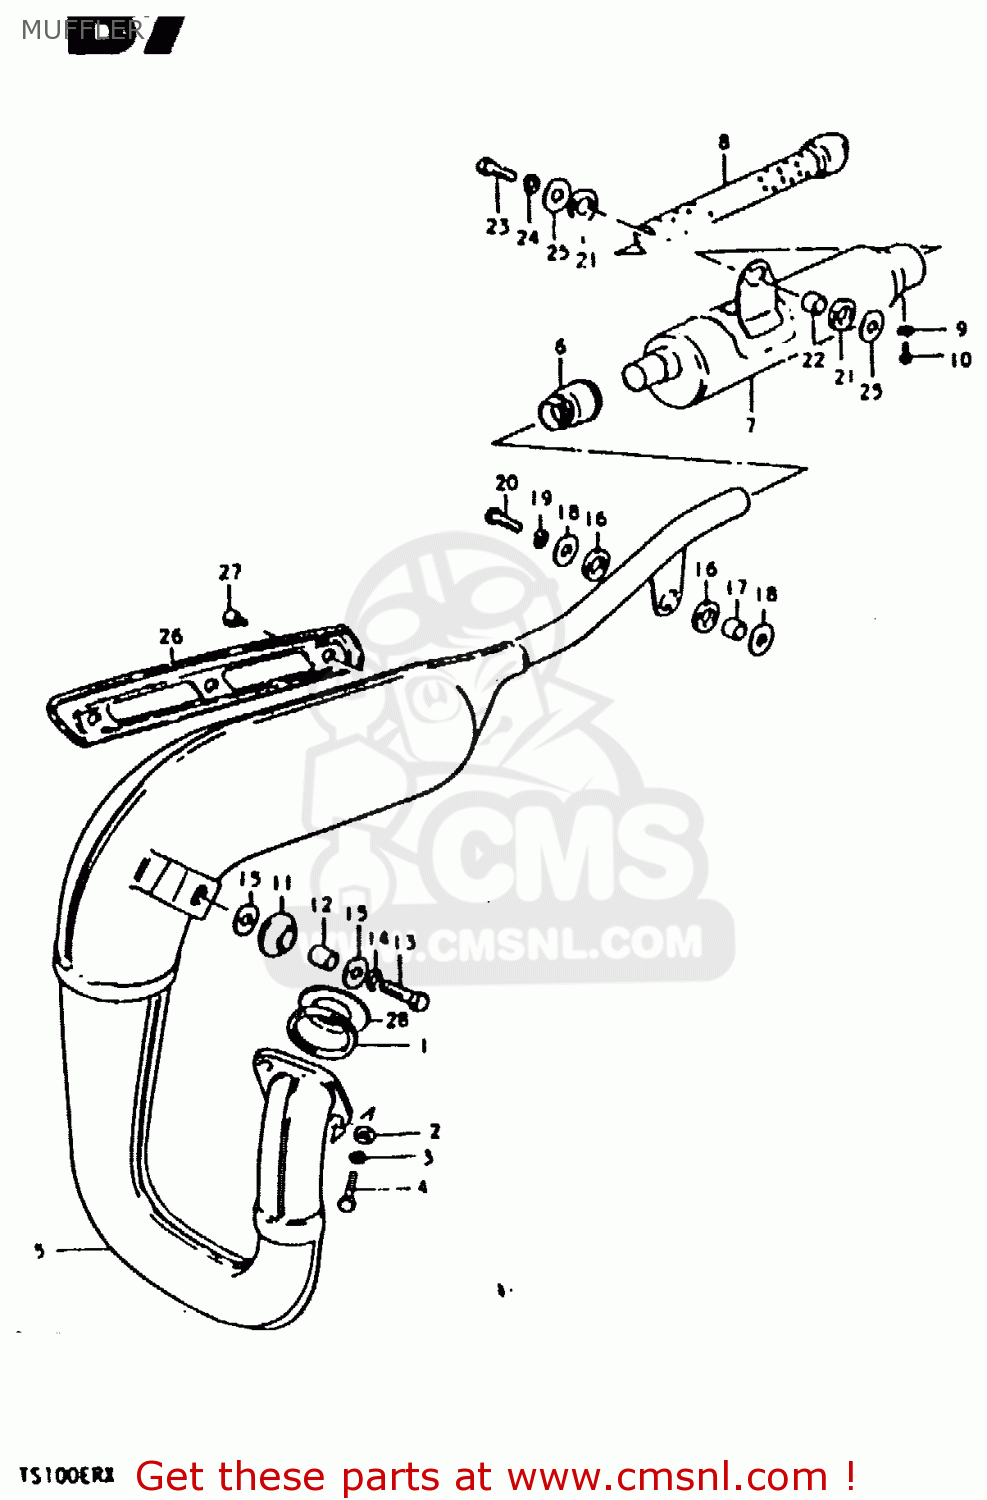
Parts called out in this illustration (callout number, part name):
1	GASKET,EXHAUST PIPE (NAS)
2	WASHER
3	LOCK WASHER
4	SCREW (6X25)
5	BODY,MUFFLER
6	CONNECTOR,MUFFLER
7	MUFFLER ASSY, 2ND
8	PIPE,BAFFLE
9	LOCK WASHER
10	SCREW
11	DAMPER,MUFFLER,FR
12	SPACER (8X12X15)
13	BOLT
14	LOCK WASHER
15	WASHER (8.7X22X2)
16	CUSHION
17	SPACER (8.6X13.8X9.8)
18	WASHER
19	LOCK WASHER
20	BOLT
21	CUSHION
22	SPACER (8.6X13.8X9)
23	BOLT
24	LOCK WASHER
25	WASHER
26	COVER,MUFFLER
27	SCREW
28	PLATE, EXHAUST PIPE
